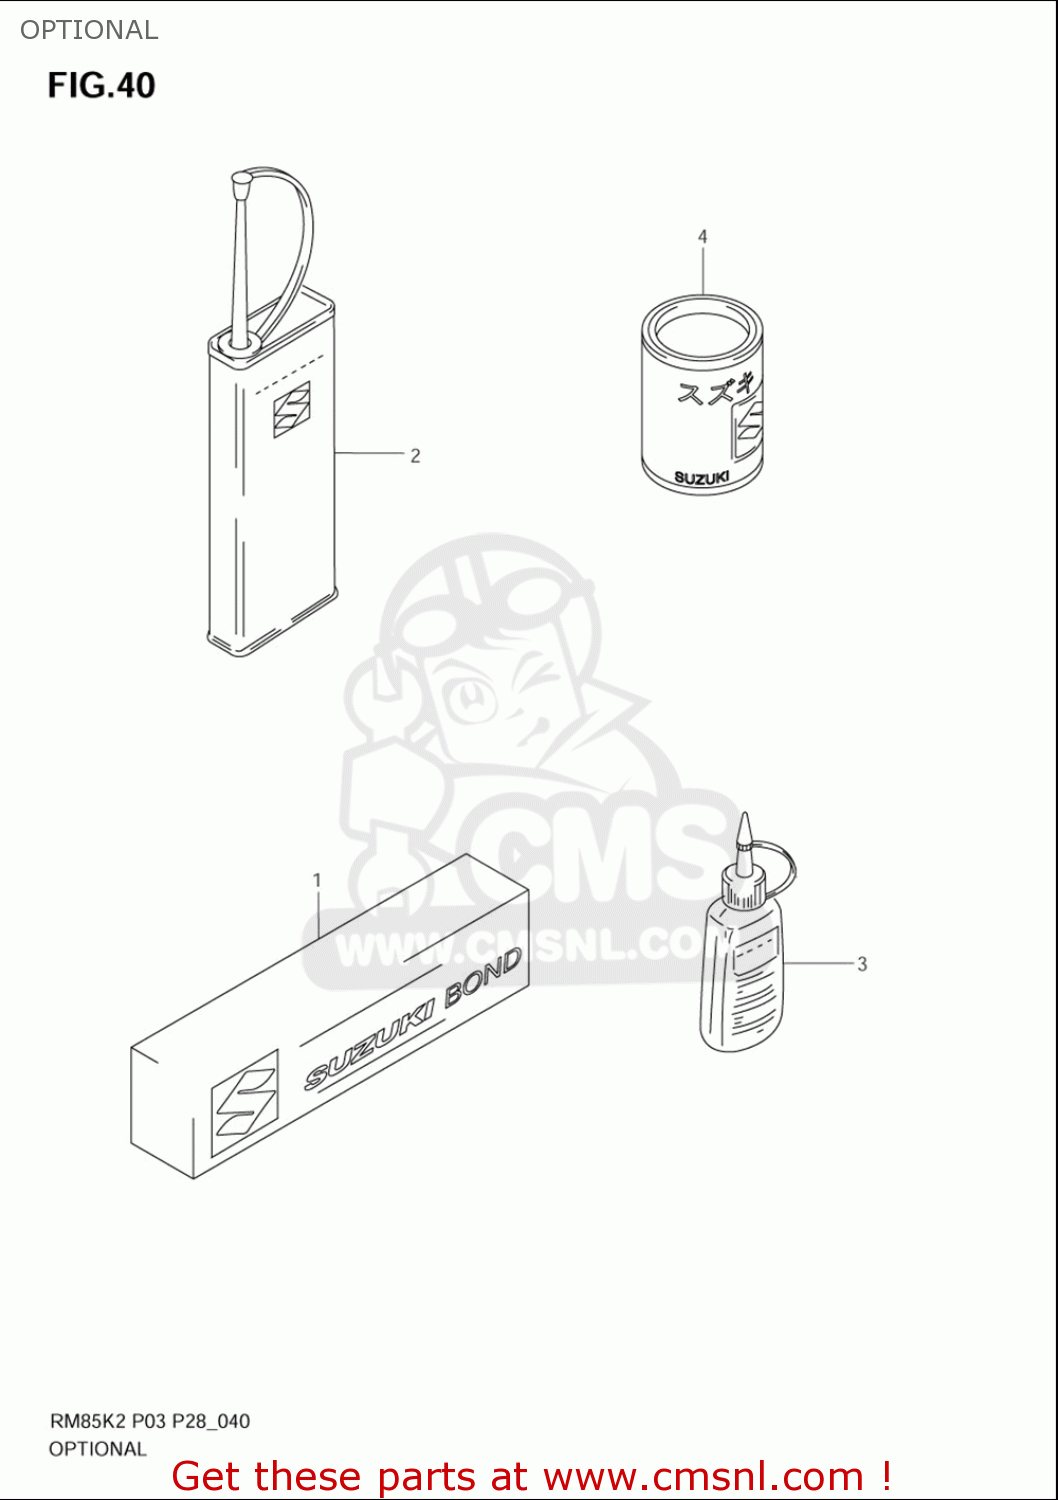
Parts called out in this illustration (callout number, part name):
1	BOND 1104
2	THREAD LOCK NO.1401 CLEAR 200G
3	THREAD LOCK NO
4	GREASE(C)EP2 LITHIUM 150G
